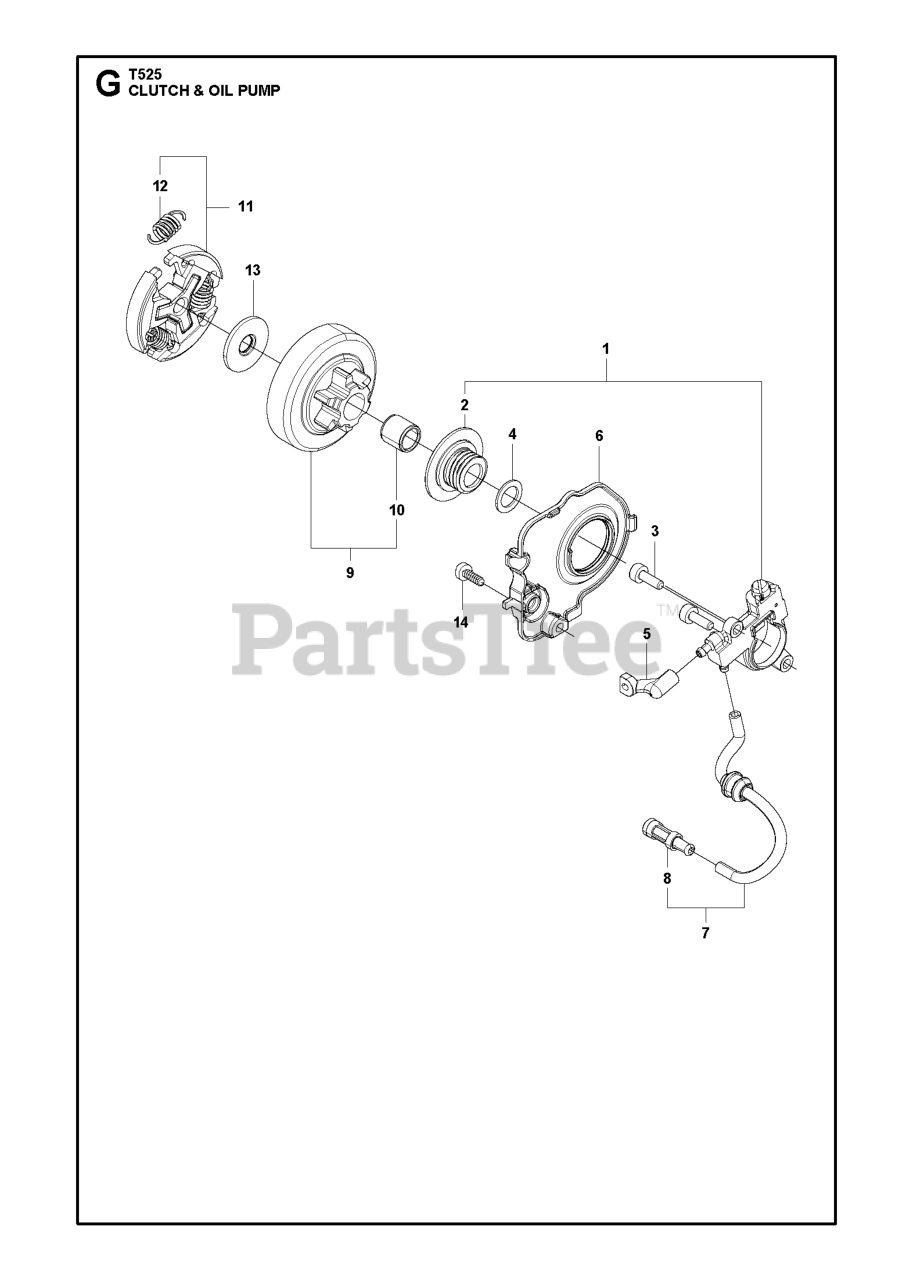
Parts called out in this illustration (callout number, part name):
1	OIL PUMP ASSY
2	OIL PUMP (WORM 199-18)
3	BOLT M4 X 12 T27
5	OIL PRESSURE HOSE
6	COVER PUMP
7	OIL HOSE ASSY
8	FILTER-ASSY 848C006740
9	CLUTCH DRUM ASSY 3/8 6 TOOTH
9	CLUTCH DRUM ASSY 1/4 8 TOOTH
10	ROLLER BEARING
11	CLUTCH 848C105121
12	SPRING T204151230
14	SCREW TP4-18X12 LOCK
